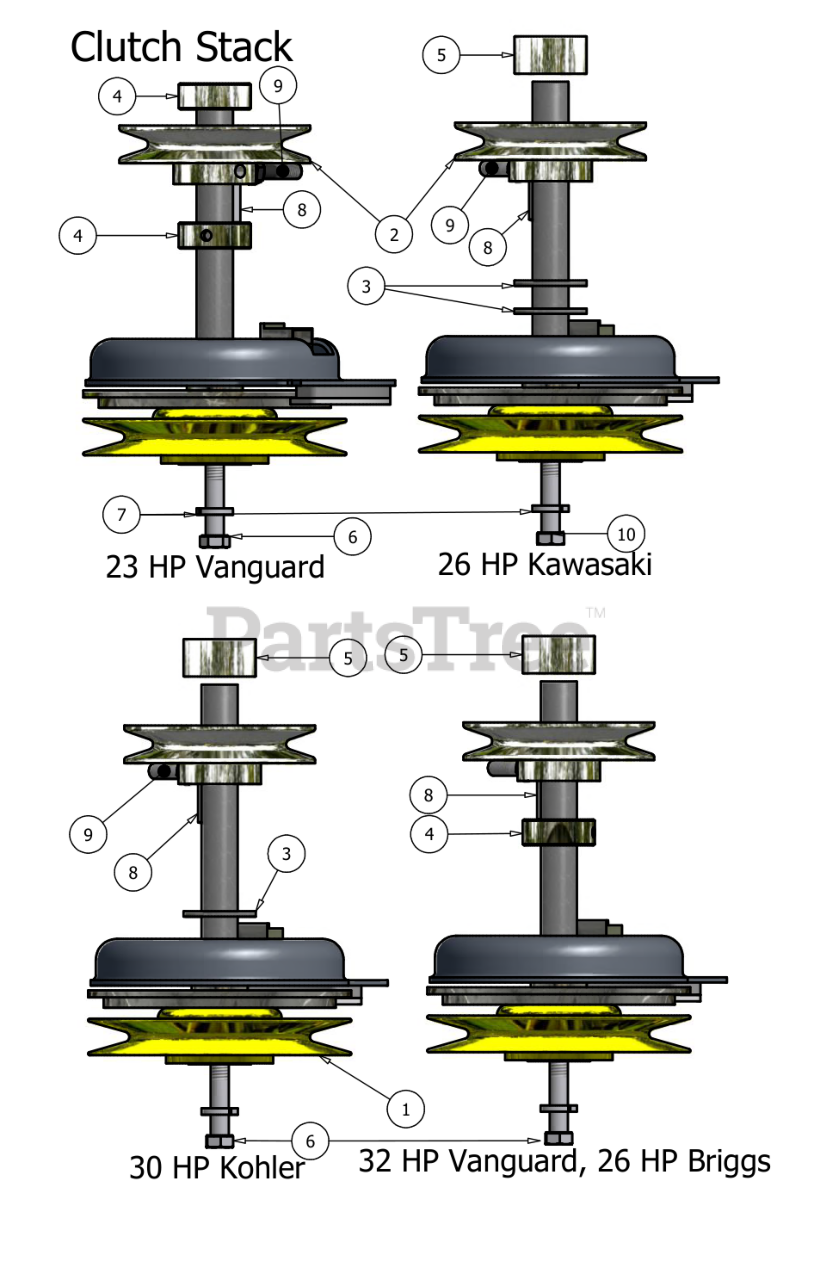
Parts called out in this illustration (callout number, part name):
1	Clutch Assembly
2	4 3/4" Motor Pulley
3	1 1/8" Flat Spacer
4	1 1/8" Collar Spacer
5	1.125 ID X.625 Spacer
6	| 7/16" x 2 1/2"Fine
7	7/16" Lock Washer
8	1/4" x 1" Key
9	3/8" Hex Bolt
10	10mm x 552 Bolt
